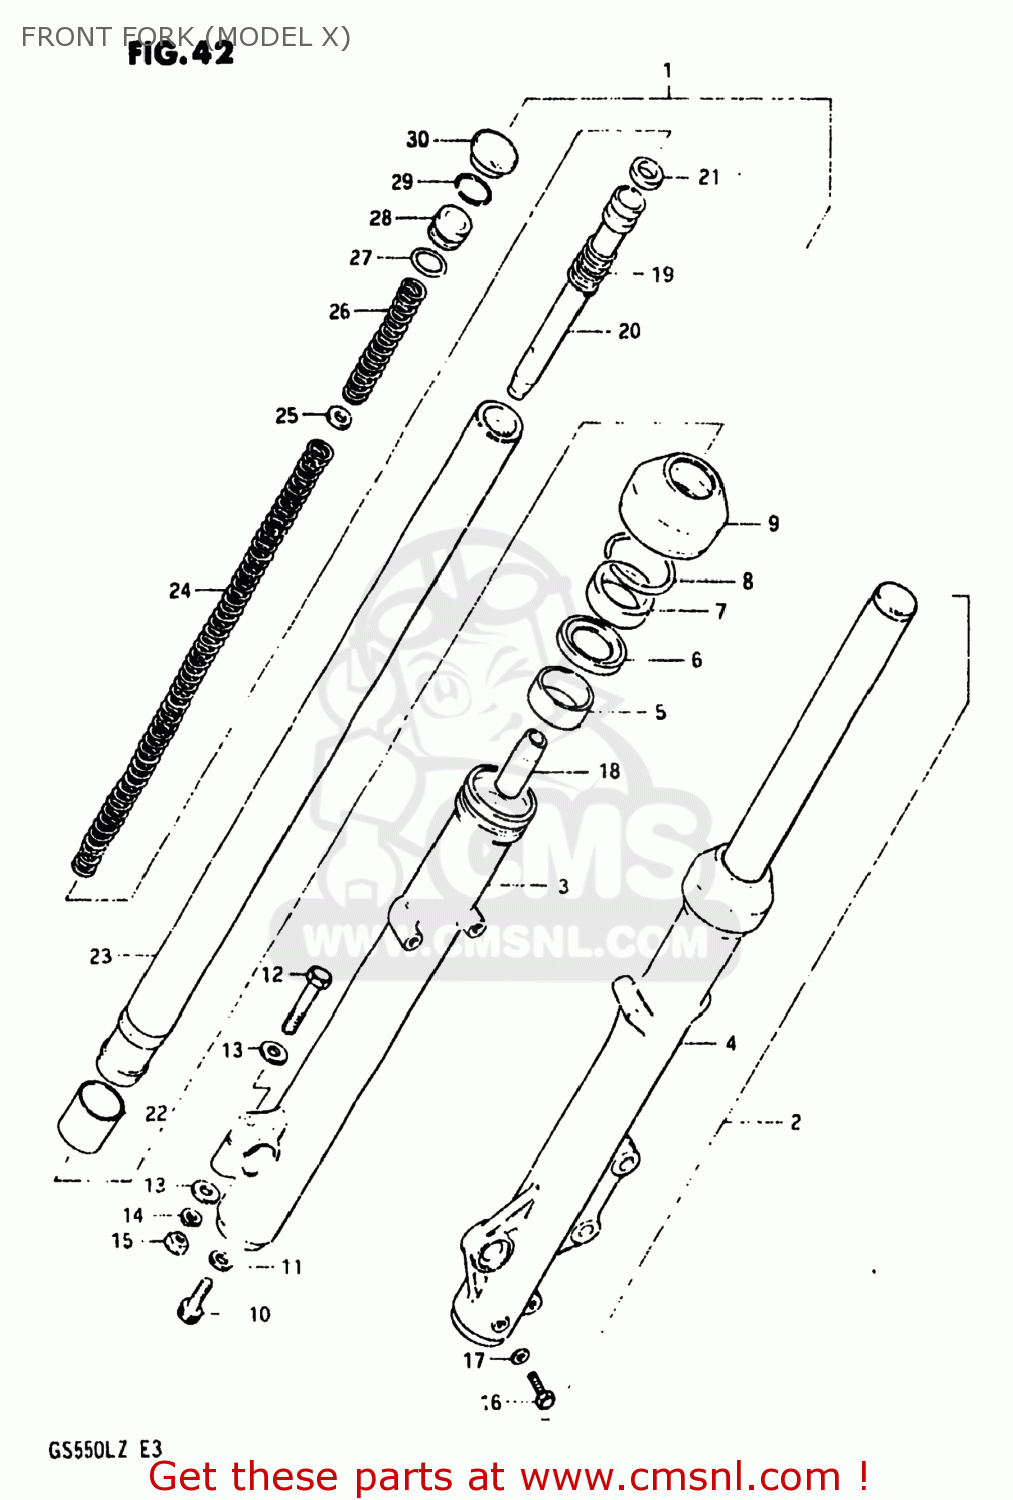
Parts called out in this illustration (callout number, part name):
1	DAMPER ASSEMBLY,RIGHT
2	DAMPER ASSEMBLY,LEFT
3	TUBE,OUTER,RIGHT
4	TUBE,OUTER,LEFT
5	BUSH,GUIDE
6	SPACER,SEAL
7	OIL SEAL,FRONT FORK
8	CIRCLIP,FORK OIL SEAL
9	BOOT
10	BOLT(8X27)
11	GASKET (NAS)
12	BOLT 8X50
13	WASHER
14	LOCK WASHER
15	NUT
16	BOLT(6X8)
17	GASKET,DRAIN,PLUG (NAS)
18	PIECE,OIL LOCK
19	SPRING,FORK REBOUND
20	CYLINDER,FRONT FORK
21	RING
22	PISTON
23	TUBE,FORK,INNER
24	SPRING,FRONT FORK
25	WASHER,SPRING
26	SPRING,FRONT FORK,UPPER
27	O-RING
28	SPRING SEAT B
29	RING,STOPPER
30	CAP
